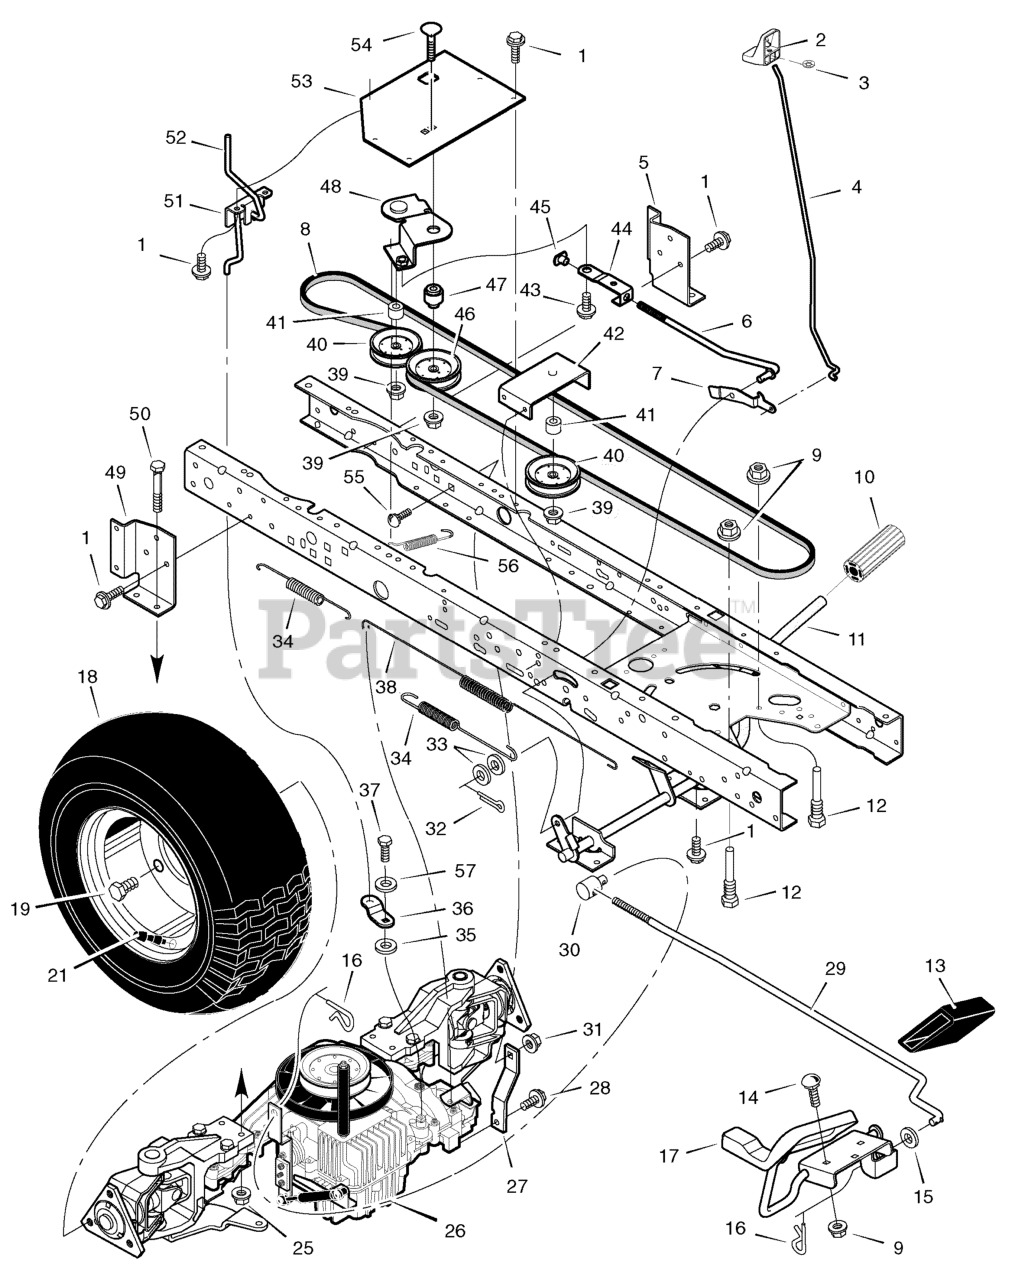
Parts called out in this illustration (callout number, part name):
1	Screw
2	Knob, Parking Brake
3	Nut, Push
4	Rod, Parking Brake
5	Bracket, Left Transaxle
6	Rod, Clutch
7	Latch, Parking Brake
8	V-Belt, Drive
9	Nut, Flange
10	Pedal, Brake/Clutch
11	Assembly, Brake Pedal
12	Screw, Guide
13	Pad, Pedal
14	Bolt, Carriage
15	Washer
16	Pin, Hair
17	Pedal Assembly, Hydro
18	Wheel & Tire Assembly
21	Stem, Valve
25	Nut, Centerlock
26	Transaxle
27	Strap, Torque
28	Screw
29	Rod, Control
30	NUT, Adjusting
31	Nut, Centerlock
32	Pin, Cotter
33	Washer
34	Spring, Extension
35	Washer
36	ARM, Disconnect
37	Capscrew
38	Spring, Brake
39	Locknut, Flange
40	Pulley, Idler
41	Spacer
42	Bracket Assembly, Idler
43	Bolt, Shoulder
44	Link, Clutch
45	Nut, Tee
46	Pulley, Idler
47	Bushing, Pivot
48	Arm Assembly, Idler
49	Bracket, Right Transaxle
51	Bracket, Disconnect
52	Rod, Disconnect
53	Bracket, Idler Pivot
54	Bolt, Carriage
55	Bolt, Carriage
56	Spring, Clutch
57	Washer
